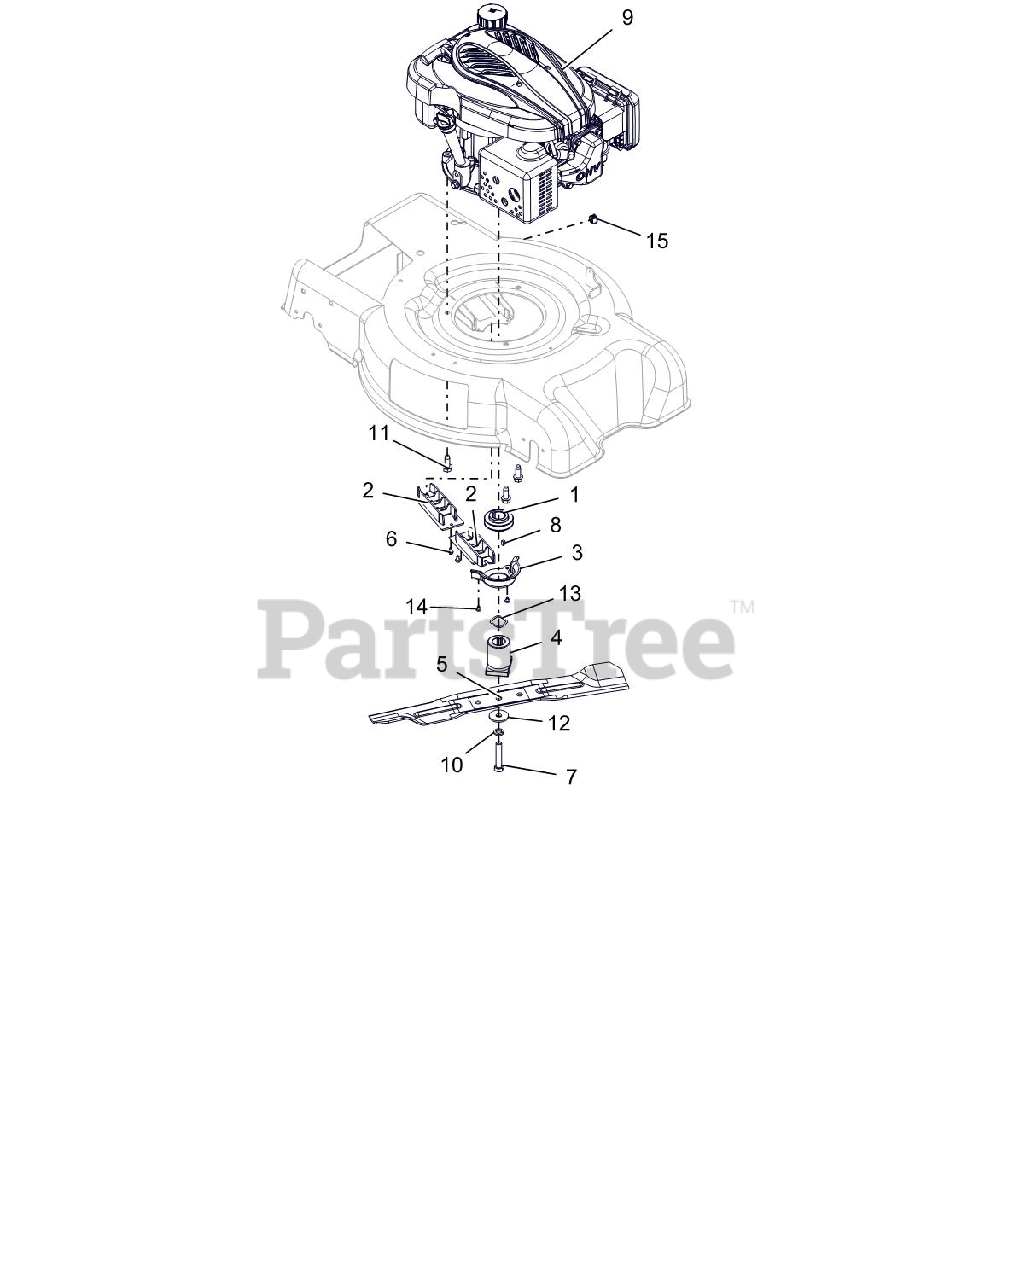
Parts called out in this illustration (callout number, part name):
1	PULLEY, GROUND DRIVE, LM
2	GUIDE, BELT INNER
3	GUIDE, BELT CRANK
4	ADAPTER, BLADE
5	BLADE, MOWER 21" HIGH LIFT
6	SCR-TAP 10-24X.375 PRE-COAT 80
7	@BLT-HEX .4375-20X2.25 GR8 YWZ
8	KEY-SQ .188X.188X.375
9	ENGINE, LONCIN 159CC VERT.
10	@WSHR-LK .44X.109 REG YWZC
11	@SCR-TAP .38-16X1.00 HWH TR YZ
12	WSHR-FL-STL .4375X1.50X.125 YZ
13	WASHER - WAVE 1.09X1.37X.016
14	SCR-TAP 10-24X.25 CRSLPH TR YZ
15	PLUG, DOME-BLACK, .625 DIA
